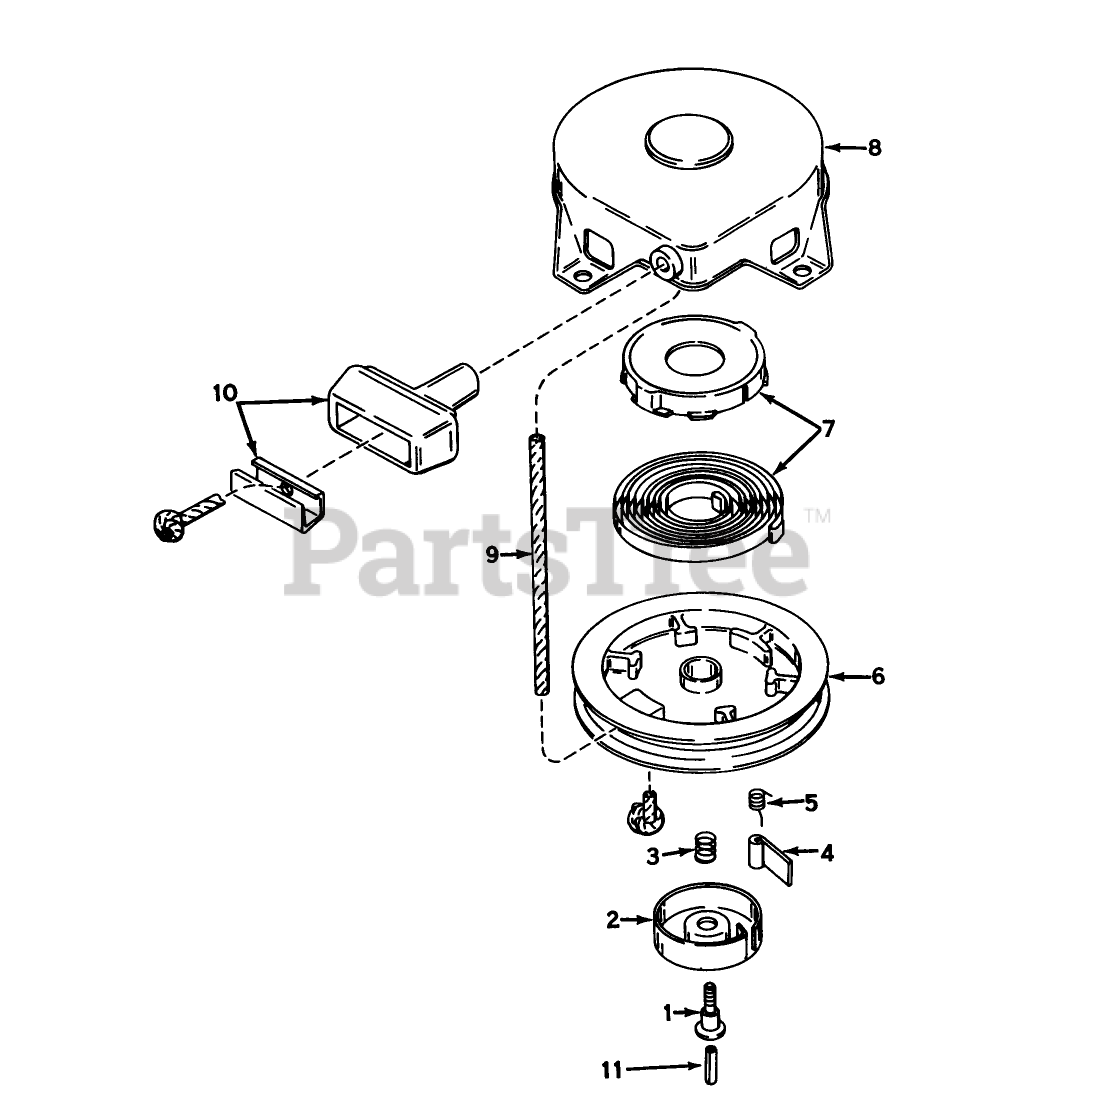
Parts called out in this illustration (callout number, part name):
1	Screw
2	Retainer
3	Spring-Brake
4	Dog-Starter
5	Spring-Dog
6	Pulley
7	Spring Keeper Assy
8	STARTER HOUSING ASSY
9	Rope Starter
10	Assy., Starter
11	Centering
